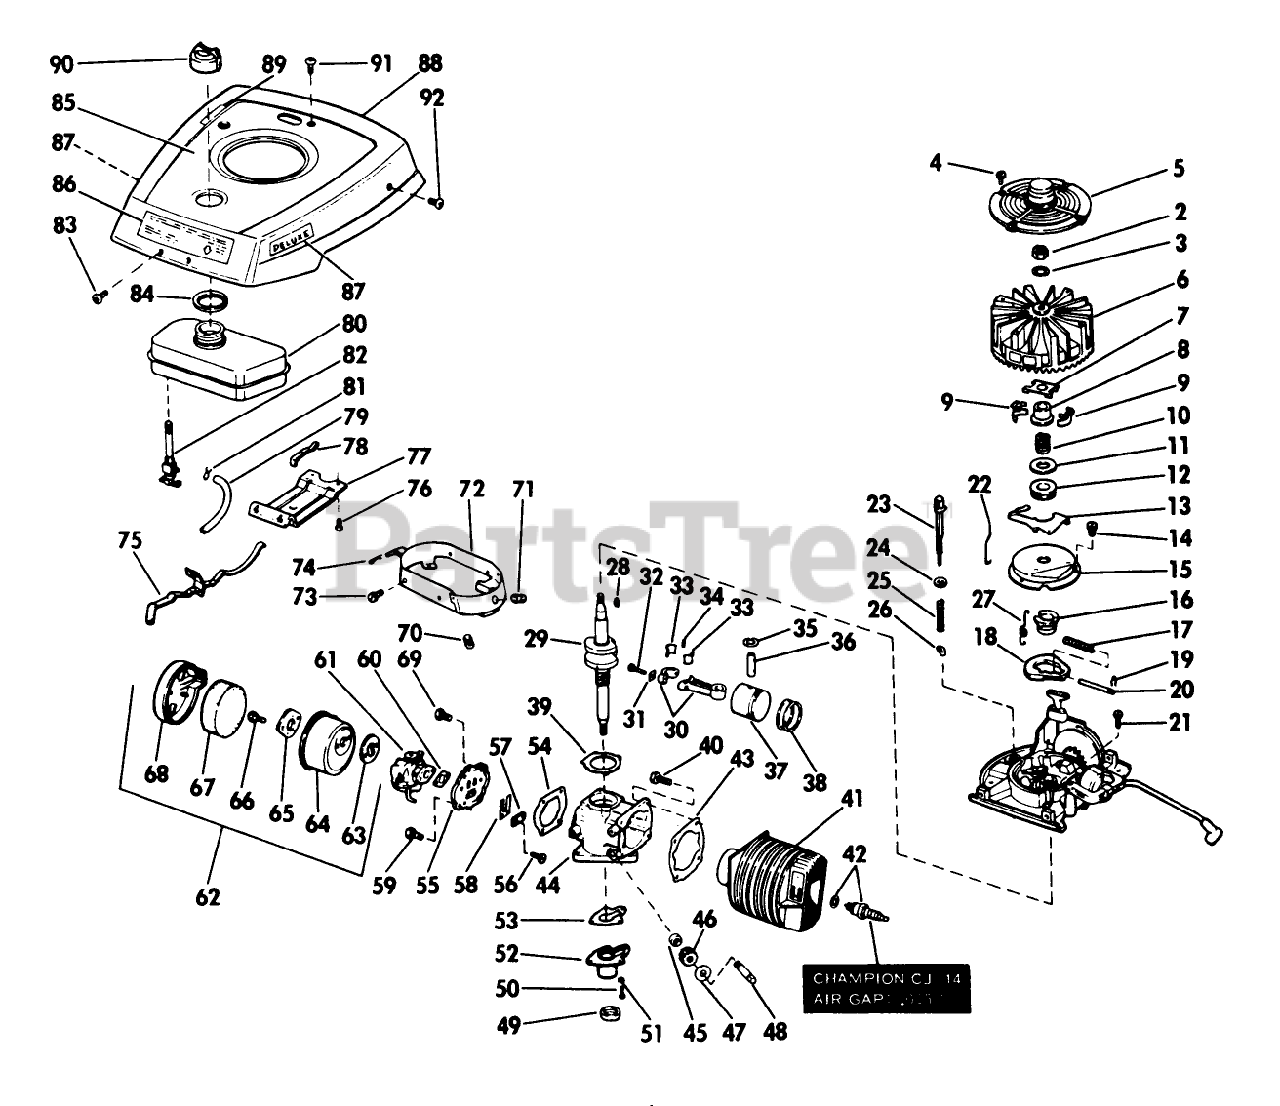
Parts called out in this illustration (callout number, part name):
4	SCREW F
5	Screen Cup
6	FLYWHEEL S
8	COLLAR S
10	SPRING S
12	THRUST COLLAR S
13	LEVER-GOVERNOR S
14	SCREW S
15	DUST COVER S
16	SPARK ADV. S
17	SPARK ADV. SPRING S
18	FLYWEIGHT S
19	SPARK ADJ. SPRING
20	PIN,SPARK ADV. S
25	SPRING S
33	LINER ASM
35	RING-RETAINING
39	GASKET S
42	Spark Plug Gasket
43	GASKET S
46	GEAR, DR SHAFT S
47	THRUST WASHER
52	GEAR COVER S
53	GASKET-CVR S
54	GASKET S
55	REED PLATE AY. S
57	PLATE-BACKUP, REED
59	SCREW S
60	GASKET S
63	GASKET S
64	FILTER CHAMBER S
66	SCREW S
67	AIR FIL.ELEM S
68	CHAMBER AY S
69	SCREW S
71	NUT-CLIP
73	SCREW S
76	SCREW S
79	GAS LINE
81	CLAMP - HOSE S
82	VALVE&SCREEN SM
91	SCREW F
92	SCREW S
